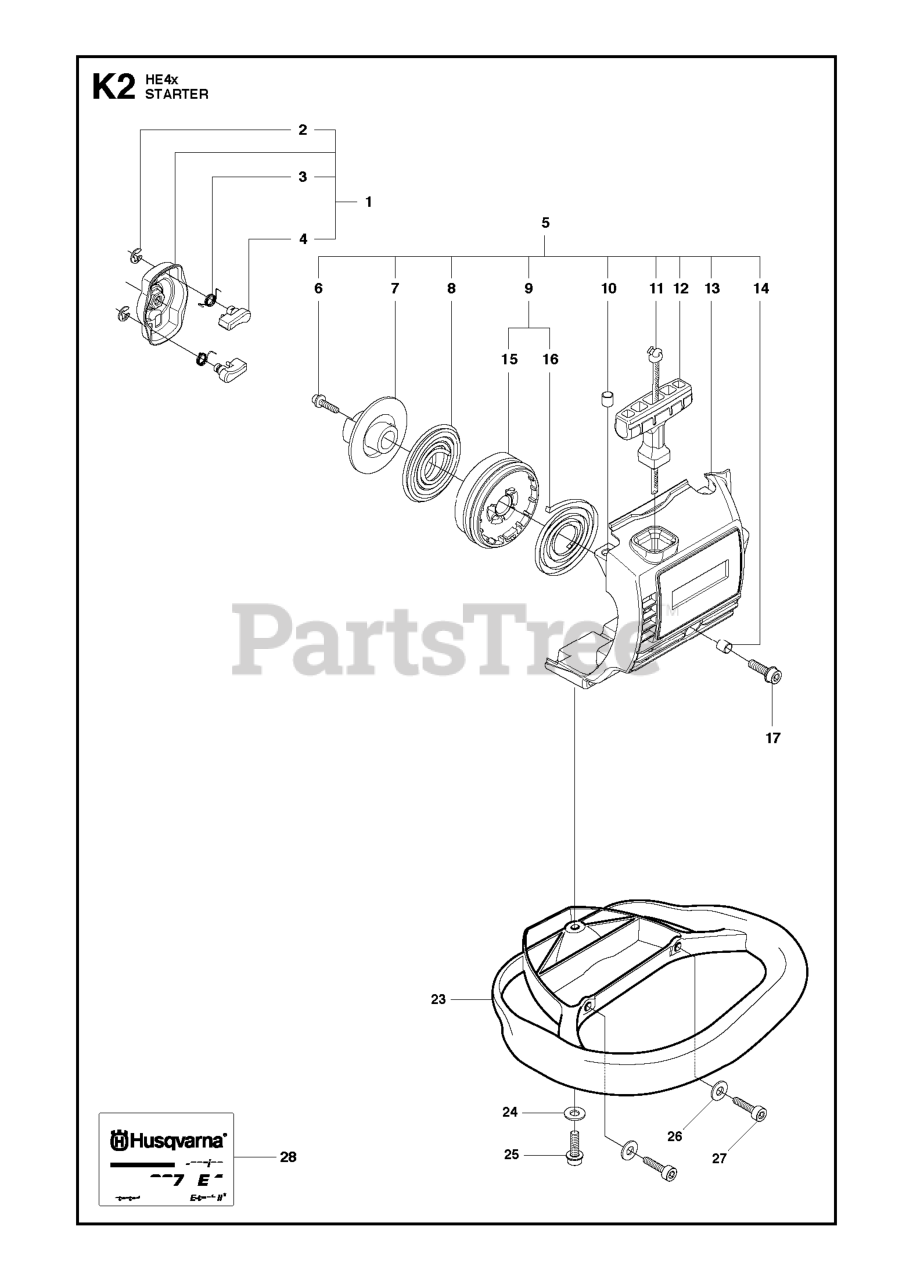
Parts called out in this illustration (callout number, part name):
1	STARTER PAWL BRIDGE
4	STARTER PAWL
5	RP STARTER ASSY
7	WHEEL
8	BALANCING SPRING
9	STARTER PULLEY
10	SPACING SLEEVE
11	STARTER ROPE
12	STARTER HANDLE
13	RP STARTER HOUSING
14	SPACING SLEEVE
15	STARTER PULLEY
17	SCREW IHSCFM
28	LABEL
